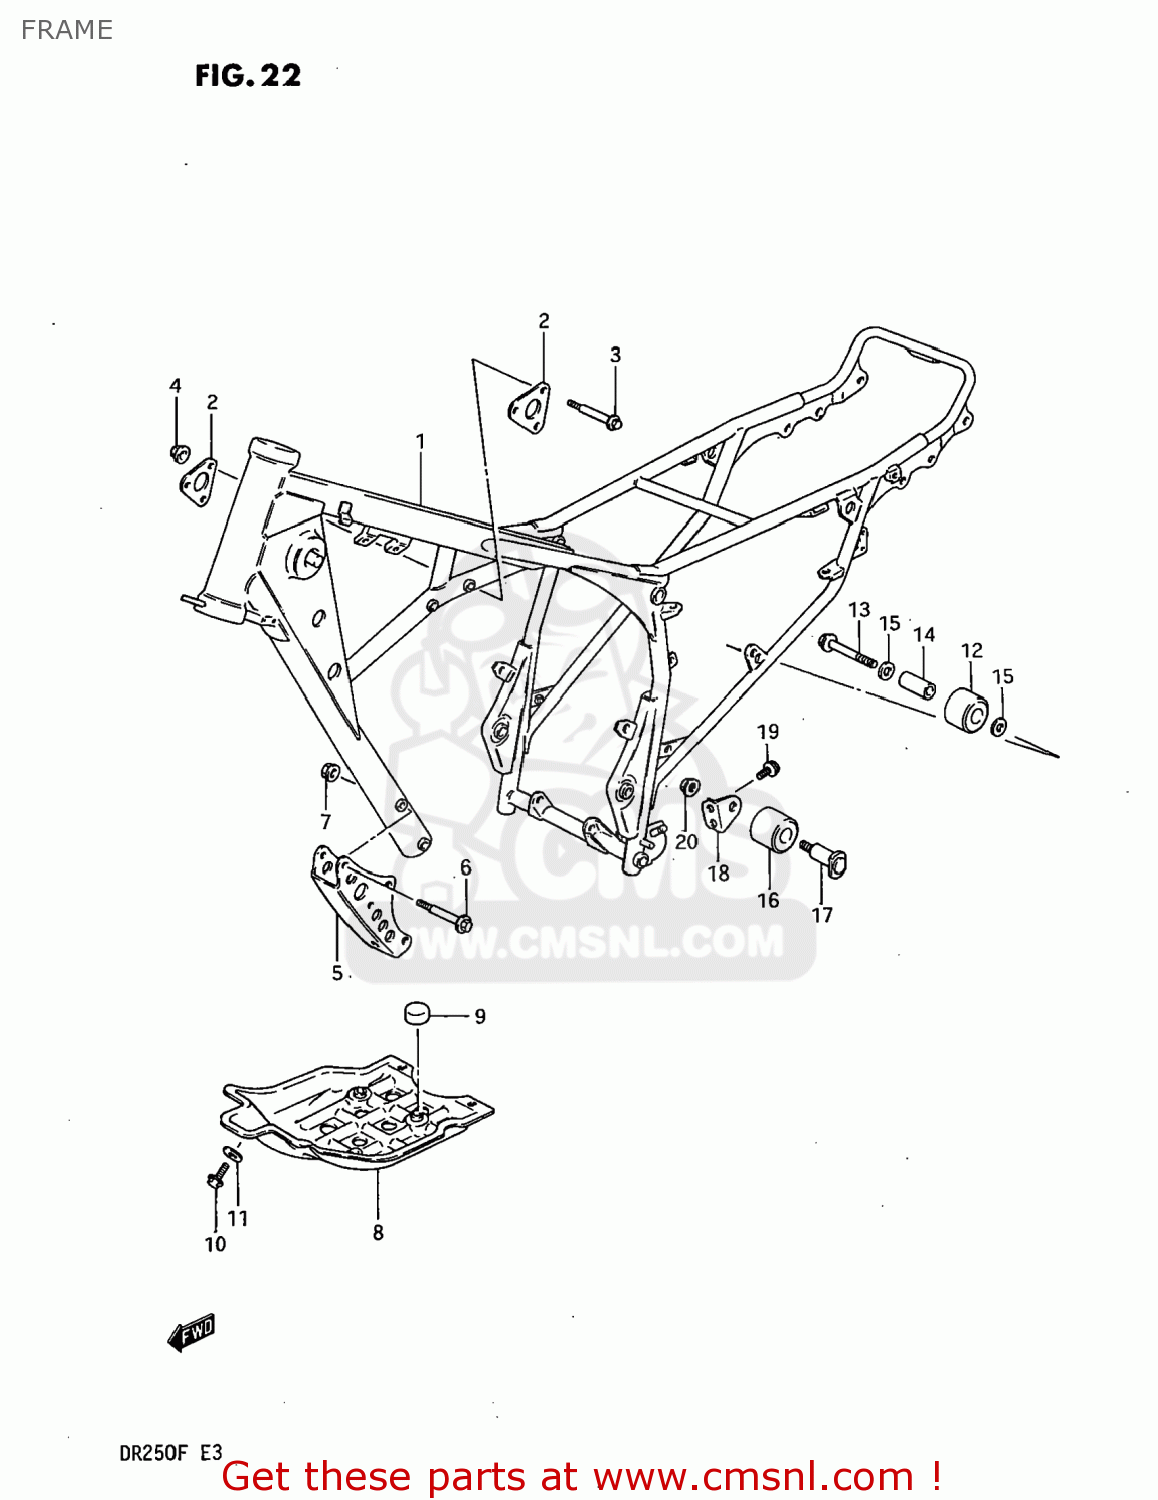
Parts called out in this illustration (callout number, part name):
1	FRAME
2	PLATE,ENGINE MOUNT UPR
3	BOLT(8X50)
4	NUT
5	PLATE,ENGINE MOUNTING
6	BOLT 8X67
7	NUT
8	PROTECTOR,ENGINE
9	CUSHION
10	BOLT 6X12
11	WASHER
12	ROLLER,CHAIN LENGTH CONTROL
13	BOLT(8X45)
14	SPACER,CHAIN LENGTH ROLLER
15	WASHER
16	ROLLER,CHAIN LENGTH CONTROL
17	ROLLER,CHAIN
18	BRACKET,LOWER
19	BOLT
20	NUT
